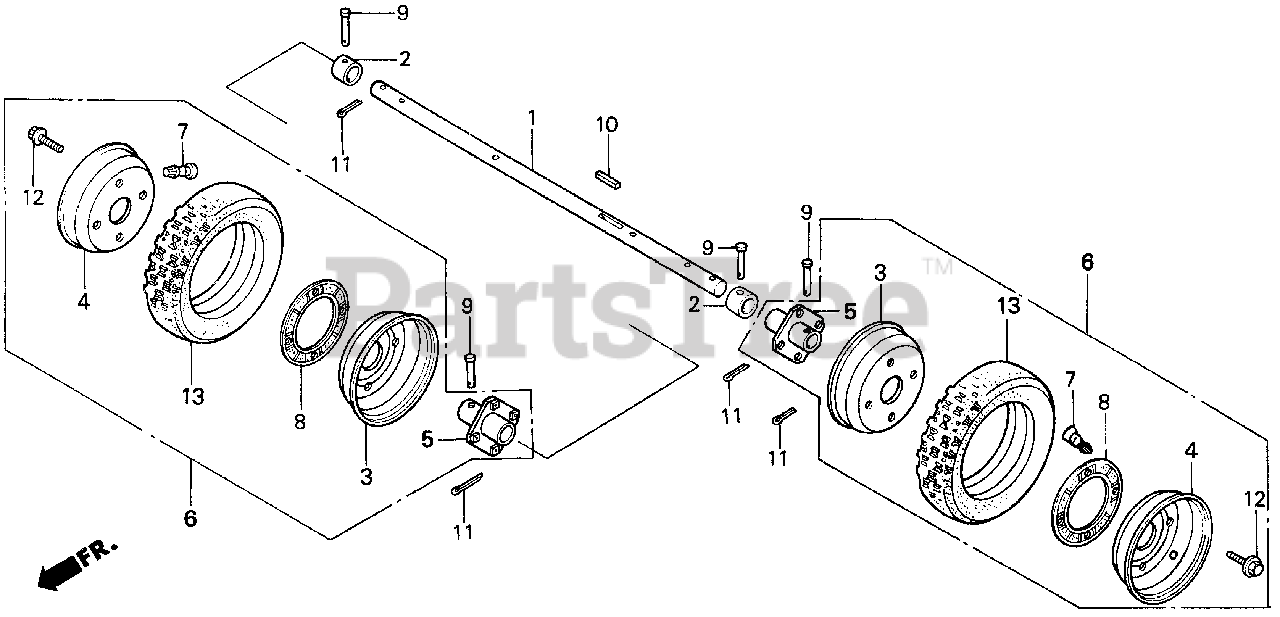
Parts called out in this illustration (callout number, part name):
1	SHAFT, WHEEL
2	COLLAR, WHEEL SHAFT
3	WHEEL A (3SPWX6DCT)
4	WHEEL B (3SPWX6DCT)
5	HUB, TIRE (HA-TYPE)
6	TIRE ASSY. (14X4.0-6) (B-905)
7	VALVE, RIM (SCHRADER)
7	VALVE, RIM (BS)
7	VALVE, RIM (TAIHEIYO)
8	GASKET (U-75)
9	PIN (6.2X38)
10	KEY (5X5X21)
11	PIN, COTTER (3.0X18)
12	BOLT, FLANGE (8X16)
13	TIRE (14X4.0-6)
